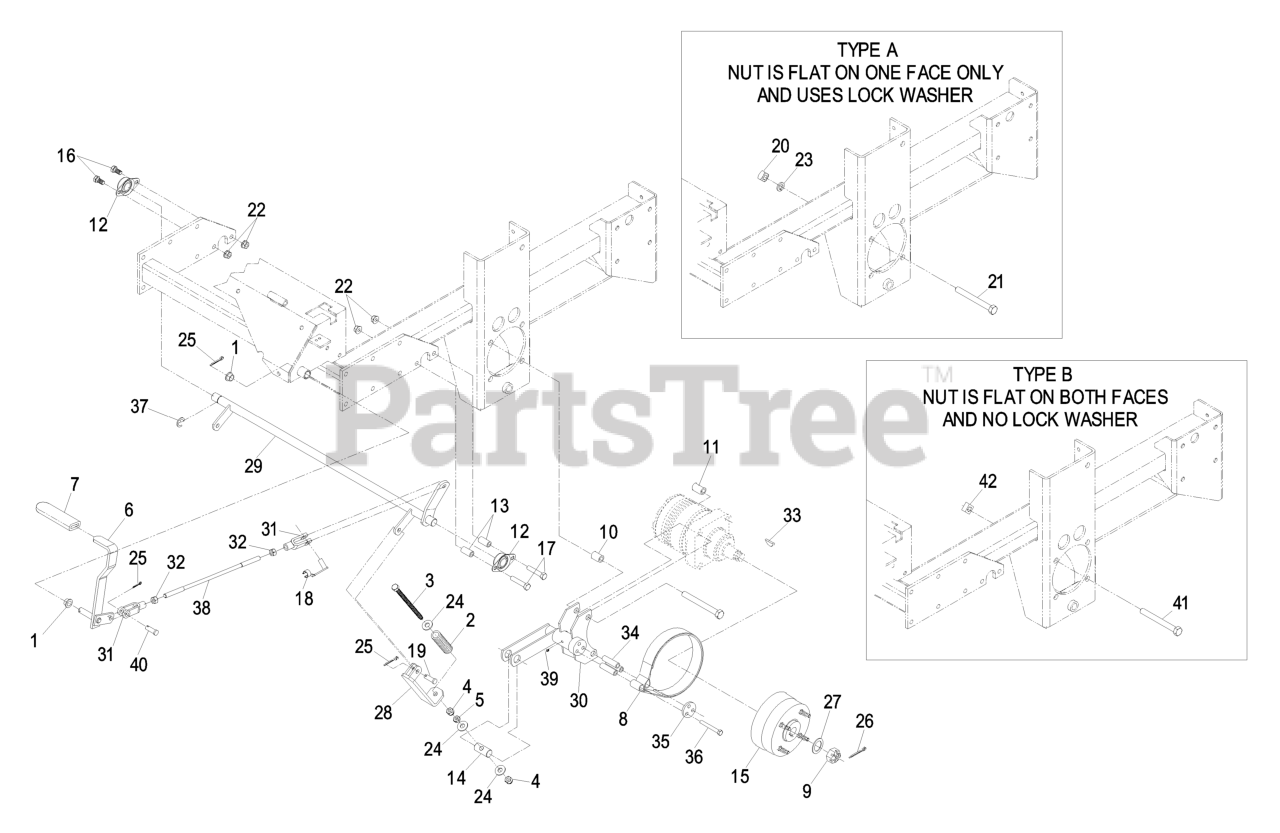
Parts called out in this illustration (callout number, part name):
1	BEARING-CONTROL
2	SPRING-COMPRESSION
3	BOLT-TAP, HH
4	NUT-LOCK, NI
5	NUT-JAM
6	BRAKE LEVER AND GRIP ASM
7	GRIP-LEVER
8	BAND,BRAKE
10	SPACER-WHEEL, SHORT
11	SPACER-WHEEL, LONG
12	BEARING-FLANGE, SIDE
13	SPACER-RETAINER, BRAKE
14	PIN-TRUNION
15	WHEEL HUB ASM
16	SCREW-HH
17	SCREW-HH
18	PIN-SPRING, CLEVIS
19	PIN-CLEVIS
21	SCREW-HH
22	NUT-HHF, WHIZ
23	WASHER-LOCK
24	WASHER-FLAT
25	PIN-COTTER
26	PIN-COTTER
27	WASHER-SPACER
28	LINKAGE-BRAKE, LOWER
29	SHAFT-BRAKE
30	BRAKE-NARROW
31	YOKE-LINKAGE, BRAKE
32	NUT-HEX
33	KEY-WOODRUFF
35	RETAINER-BAND, BRAKE
36	SCREW-HH
38	ROD-BRAKE
39	FITTING-GREASE
40	PIN-CLEVIS
41	SCREW-HH
42	NUT-SQUARE, SPECIAL
